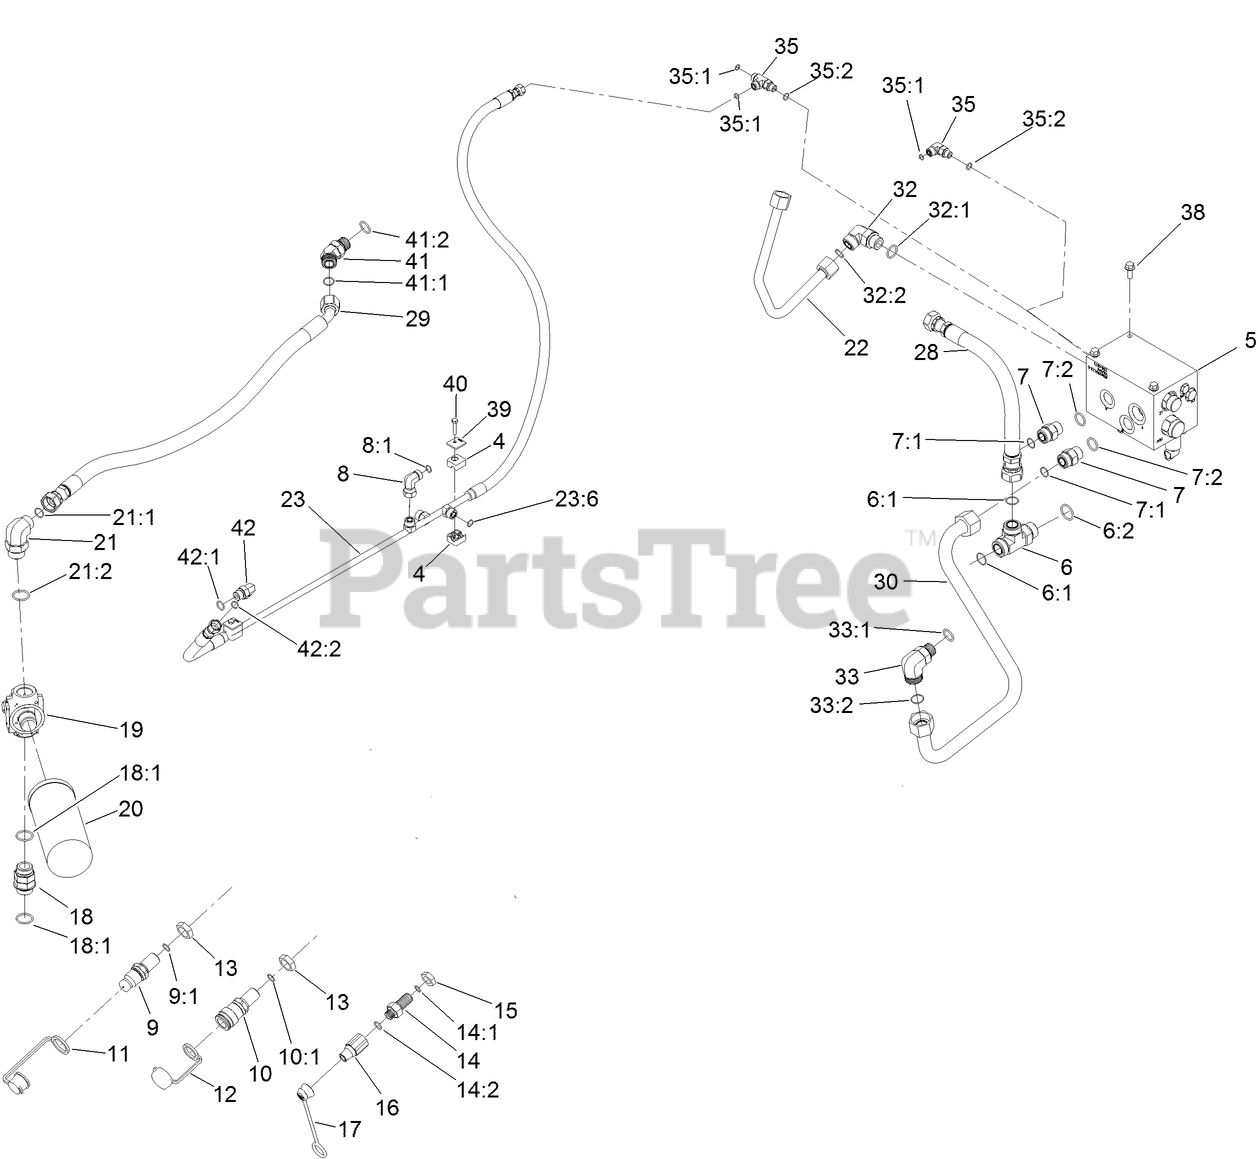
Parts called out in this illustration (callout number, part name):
4	CLAMP-TUBE
5	AUX MANIFOLD ASM
6	FITTING-TEE
6:1	O-RING
6:2	O-RING
7	FITTING-HYD, STRAIGHT
7:1	O-RING
7:2	O-RING
8	FITTING-HYD
8:1	O-RING
9	BULKHEAD NIPPLE ASM
9:1	O-RING
10	BULKHEAD COUPLER ASM
10:1	O-RING
11	CAP-DUST, NIPPLE
12	CAP-DUST, COUPLER
13	NUT-LOCK, BULKHEAD
14	UNION-BULKHEAD
14:1	O-RING
14:2	O-RING
15	NUT-BULKHEAD
16	FITTING-QUICK COUPLING
17	CAP-DUST, NIPPLE
18	FITTING-STRAIGHT
18:1	O-RING
19	HEAD-FILTER
20	ELEMENT-FILTER
21	FITTING-ELBOW 90
21:1	O-RING
21:2	O-RING
22	HYD TUBE ASM
23	HYD TUBE ASM
23:6	O-RING
28	HYD HOSE ASM
29	HYD HOSE ASM
30	HYDRAULIC TUBE ASM
32	FITTING-ELBOW-90
32:1	O-RING
32:2	O-RING
33	FITTING-ELBOW 90
33:1	O-RING
33:2	O-RING
35	FITTING-ELBOW, 90 DEG
35:1	O-RING
35:2	O-RING
38	SCREW-HHF
39	PLATE-CLAMP,TUBE
40	SCREW-HH
41	FITTING-45 DEG
41:1	O-RING
41:2	O-RING
42	FITTING-ELBOW, 90 DEG
42:1	O-RING
42:2	O-RING
